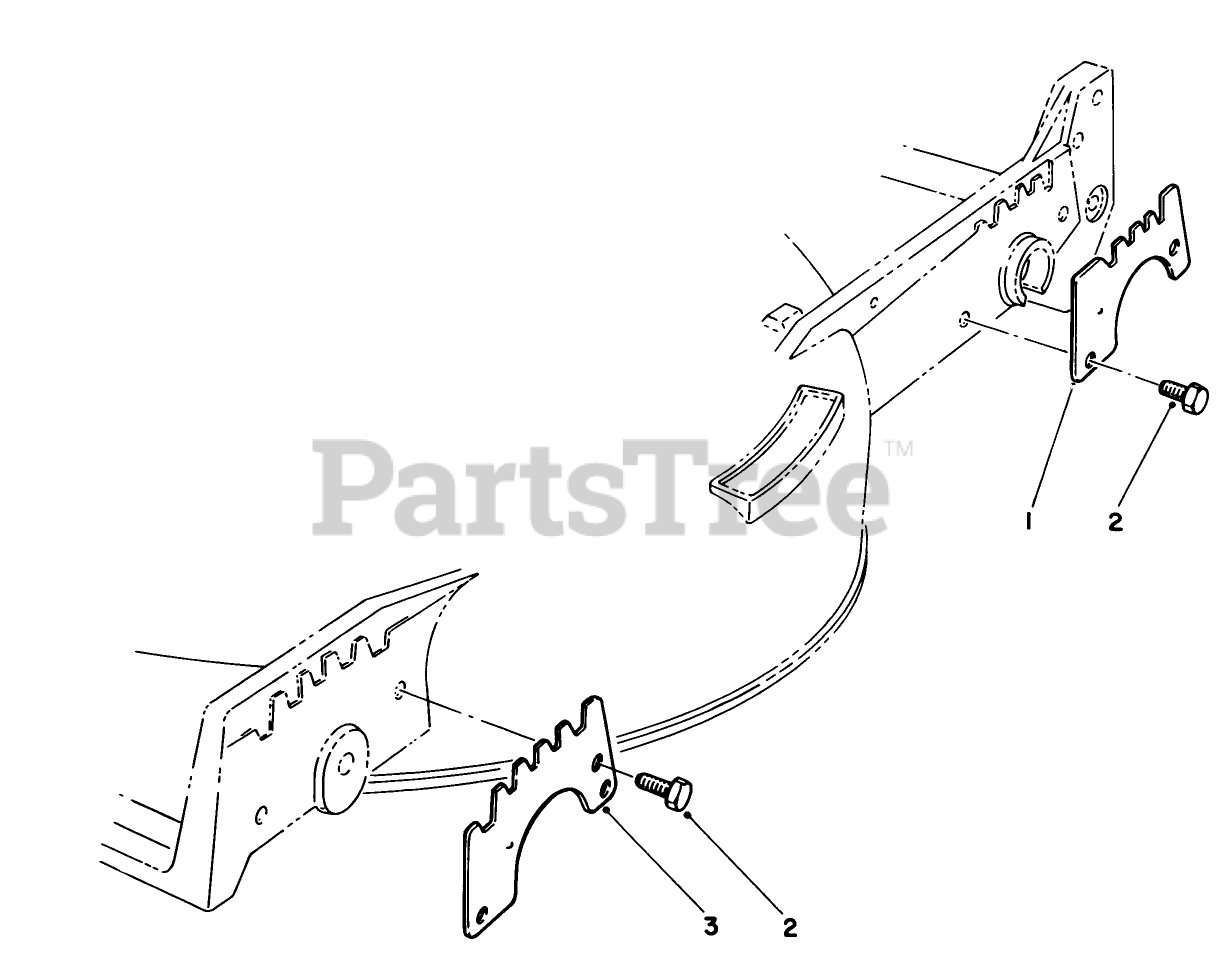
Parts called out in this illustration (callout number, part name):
1	WEAR PLATE,REAR
2	SCREW-HWH
3	WEAR PLATE
